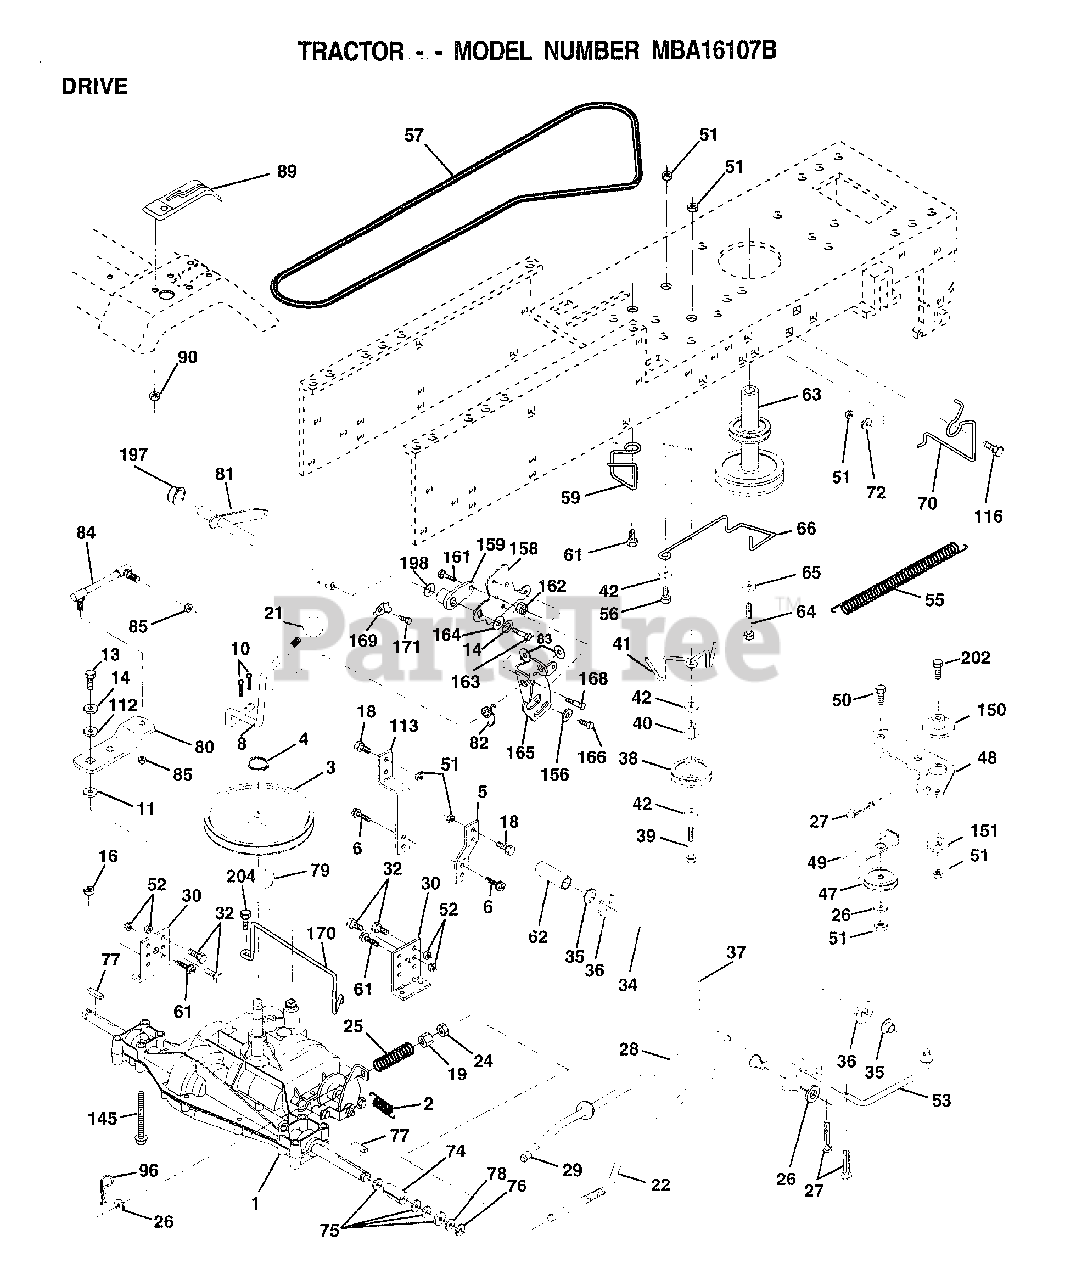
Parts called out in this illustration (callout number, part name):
2	SPRING.BRAKE.RETU
3	PULLEY TRANS
5	STRAP TORQUE
6	SCREW
8	ROD.SHIFT.FENDER.ADJ.LT.CRD
10	PIN COTTER 1/8
11	WASH-SHFT PLT LT
13	BOLT.1/4-28.W/PAT
14	LOCKWASHER
16	NUT
18	BOLT
19	NUT
21	KNOB T (1/2-HOLE)
22	BRAKE ROD
24	NUT
25	SPRING ROD LT
26	WASHER
27	COTTER PIN
28	ROD.BRAKE.PARK.LT
29	PLUNGER CAP T
30	BRACKET MTG TRANSAXLE
32	BOLT
34	SHAFT ASM-PEDAL F
35	NYLON BEARING
36	WASHER LT
38	FLAT IDLER PULLEY
39	BOLT
40	SPACER T
41	"KEEPER,BELT.IDLER FLAT"
42	WASHER
48	BELLCRANK.CLUTCH
49	RETAIN BELT
53	"LINK, CLUTCH T"
55	"SPRING, RETURN LT"
59	KEEPER BELT SPAN CTR
61	SCREW
62	PEDAL COVER T
63	PULLEY.ENGINE
64	BOLT
65	LOCKWASHER
66	KEEPER-BELT
70	KEEPER BELT ENG
72	WASHER
74	SPACER AXLE
75	WASHER
76	E-RING LT
77	SQUARE KEY
78	WASHER
80	"ARM.SHIFT.20""TIRE"
81	SHAFT.ASM.CROSS
82	"SPRING,TORSION"
83	WASHER
84	LINK.TRANSAXLE.PMST/DANA
85	NUT.CNT.LOCK.1/4
90	NUT
96	RETAINER M
112	WASHER LT
113	"STRAP,TORQUE"
116	BOLT RDHD 3/8-16
145	BOLT.HEX.FLGHD
150	BUSHING.BELLCRANK.GRD.DR
151	WASHER
156	WASHER.SRRTD.5/16
158	BRKT.SHIFT.MOUNT
159	HUB.SHIFT
161	BOLT T
164	WASHER.5/8X.281X10GA
165	BRKT.PIVOT.LEVER
166	SCREW.5/16-18X5/8
168	BOLT.SHOULDER.5/16-18X.561
169	PLATE.FASTENING
170	KEEPER.BELT.TRANSAXLE
171	SCREW LT
197	NYLINER SNAP-IN
198	WASHER NYLINER
202	BOLT.3/8-16X1.50
204	SCREW
